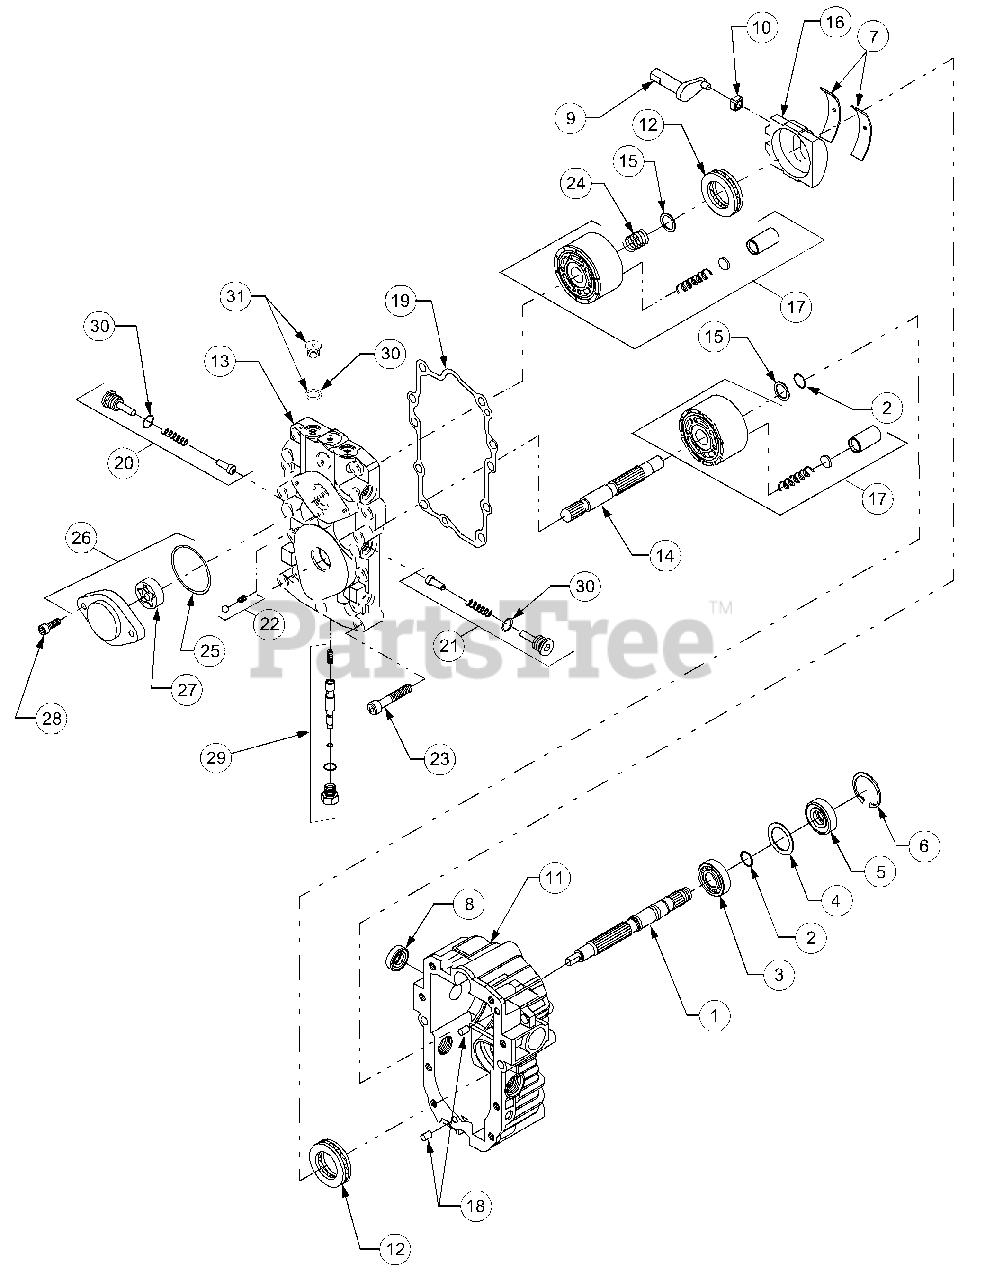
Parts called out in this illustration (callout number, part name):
1	Shaft, Pump (Splined)
2	Ring, Retaining
3	Bearing, Ball
6	Ring, Retaining
7	Bearing, Cradle
9	Arm, Trunnion
10	Guide, Slot
11	Housing Kit
12	Bearing Assembly, Thrust Ball
13	Center Section Kit
14	Shaft, Motor
15	Washer, Block Thrust
16	Swash Plate
17	Block Assembly
19	Gasket, Center Section
20	Kit, Check Valve
21	Kit, Orificed Check Valve
22	Kit, Charge Relief Valve
23	Screw, Socket Hd
24	Spring, Block
26	Kit, Charge Pump
27	Gerotor Assy
28	Screw, Socket Hd
29	Bypass Valve Kit
